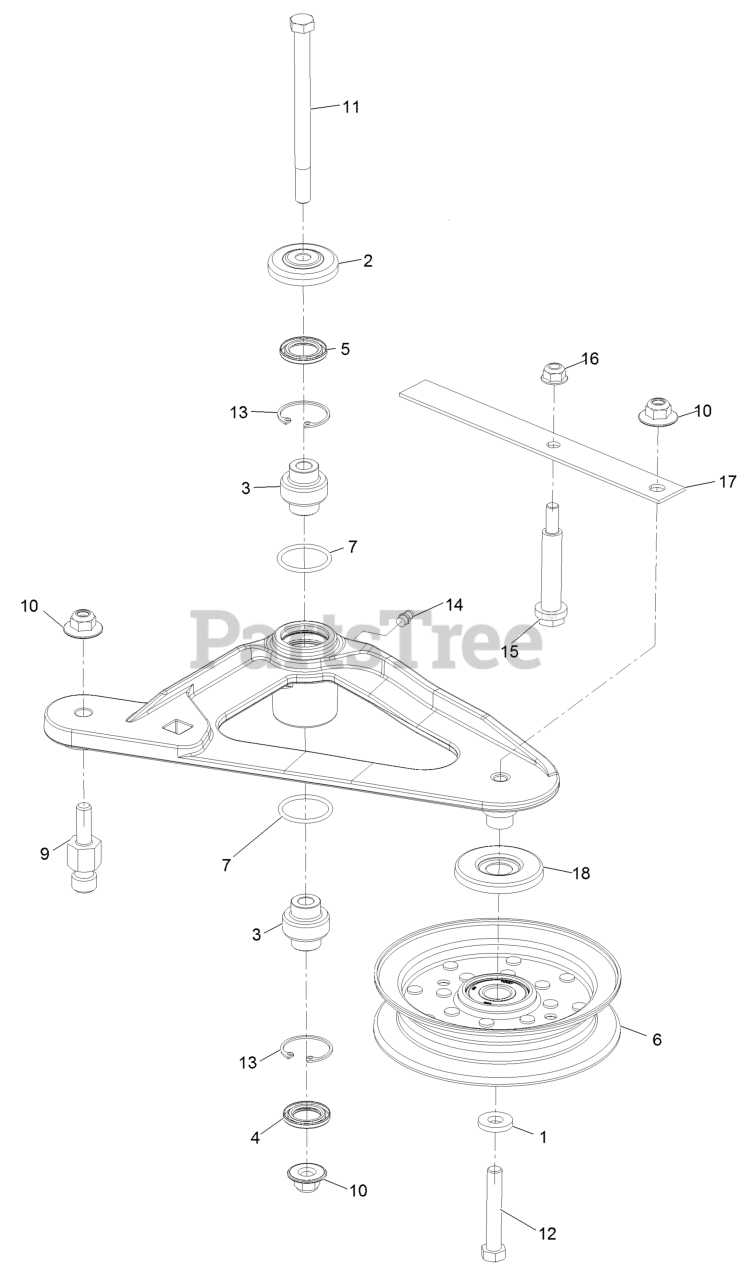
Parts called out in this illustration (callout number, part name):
2	GUARD-TOP
3	BEARING-SPHERICAL
4	SEAL-LIP, DOUBLE
5	SEAL-LIP, SINGLE
6	IDLER-PULLEY, FLAT
9	PIN-SPRING, ANCHOR
10	Nut-Nyloc 3/8-16 Flg
11	SCREW-SHOULDER, HH
12	SCREW-HH
13	RING-SNAP
14	FITTING-GREASE
15	BOLT-SHOULDER
16	NUT-HF, NI
17	SPRING-BELT
18	SHIELD-GUARD, DUST
